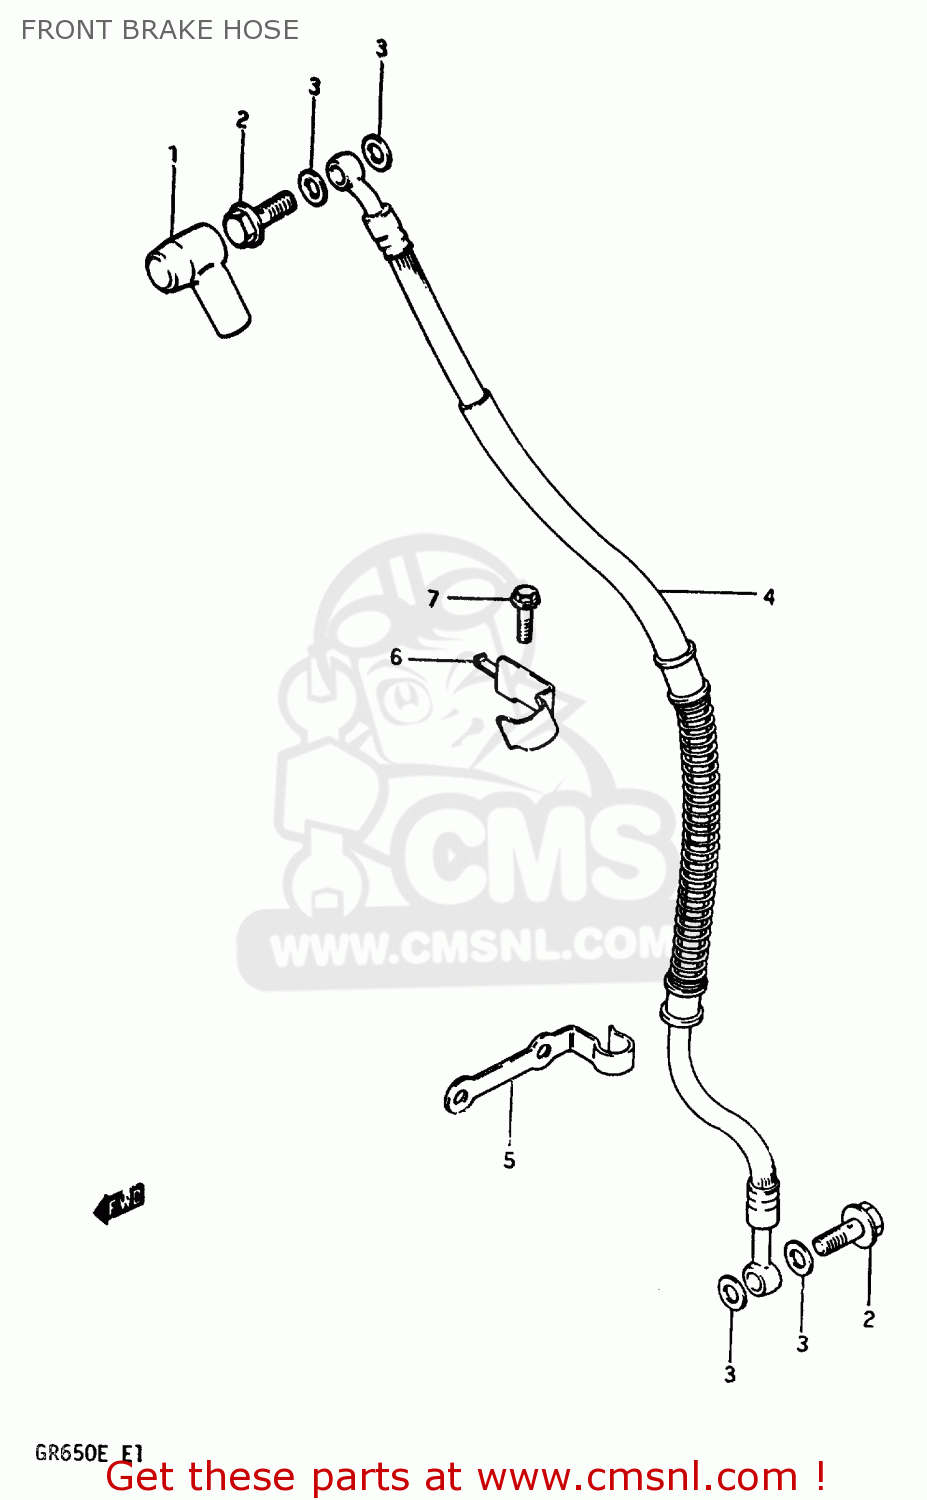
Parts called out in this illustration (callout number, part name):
1	BOOT,MASTER CYLINDER
2	BOLT UNION
3	WASHER
4	HOSE,BRAKE
5	GUIDE,BRAKE HOSE NO.2
6	GUIDE
7	BOLT
